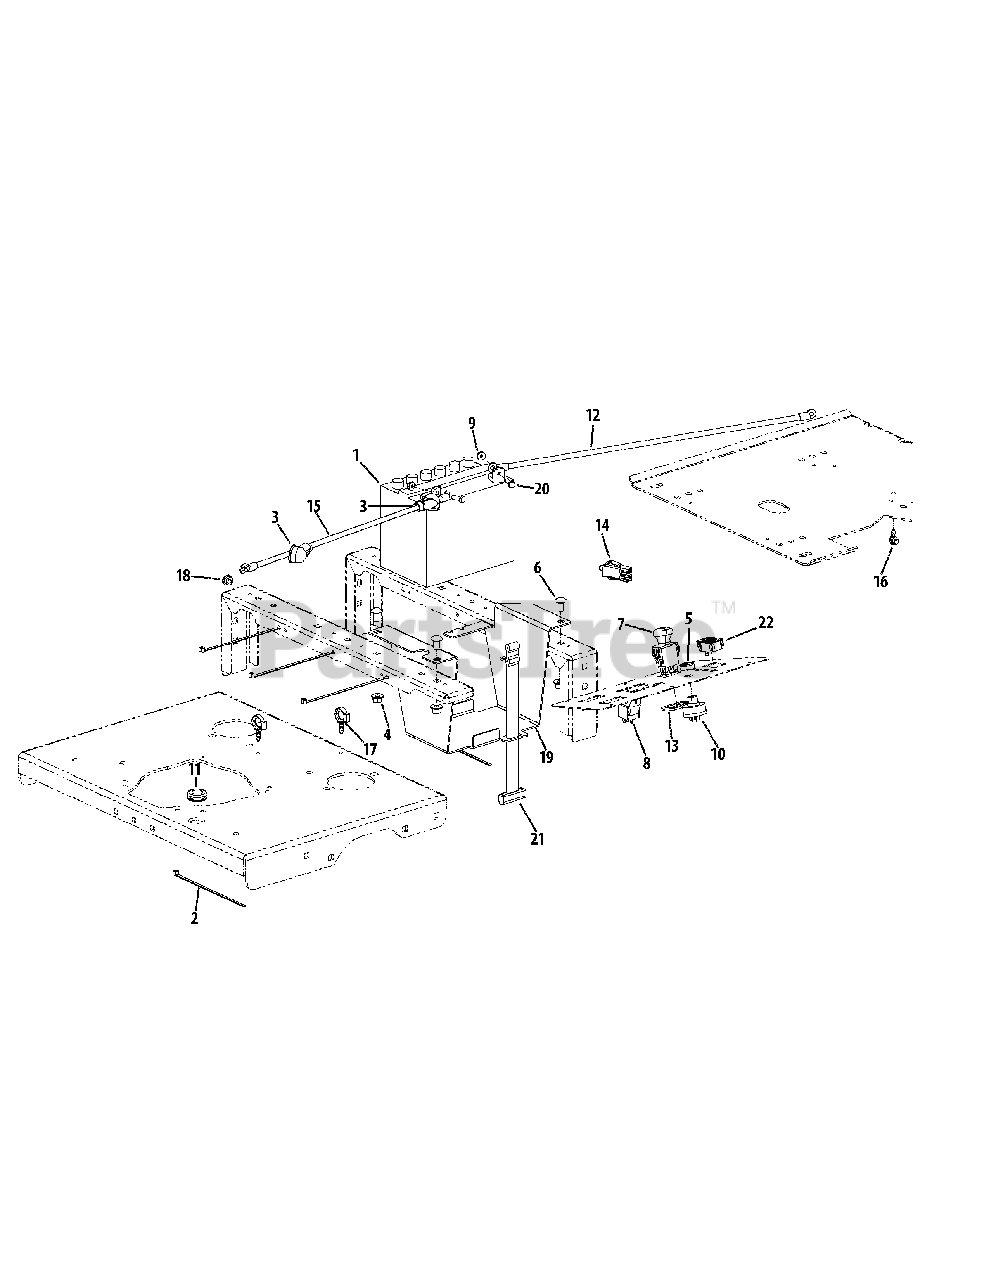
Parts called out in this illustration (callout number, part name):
2	Cable Tie
3	Boot Terminal, 1.00 x 2.50
4	Flange Counter Lock, 3/8-16
5	Ingnition Nut w/ Cap, 5/8-32
6	Carriage Bolt, 3/8-16 x .75
7	PTO Switch
9	Flange Top Lock Nut, 1/4-20
10	Ignition Switch
11	Grommet, .75
12	Batter Cable
13	PTO Switch Bracket
14	Switch
15	Batter Cable
16	Electric CDT Clip, 3/8
17	Electric CDT Clip, 5/8
18	Flange Nut, M8-1.25
19	Battery Bracket
20	Hex Screw, 1/4-20 x .75
21	Battery Strap
22	Hour Meter
